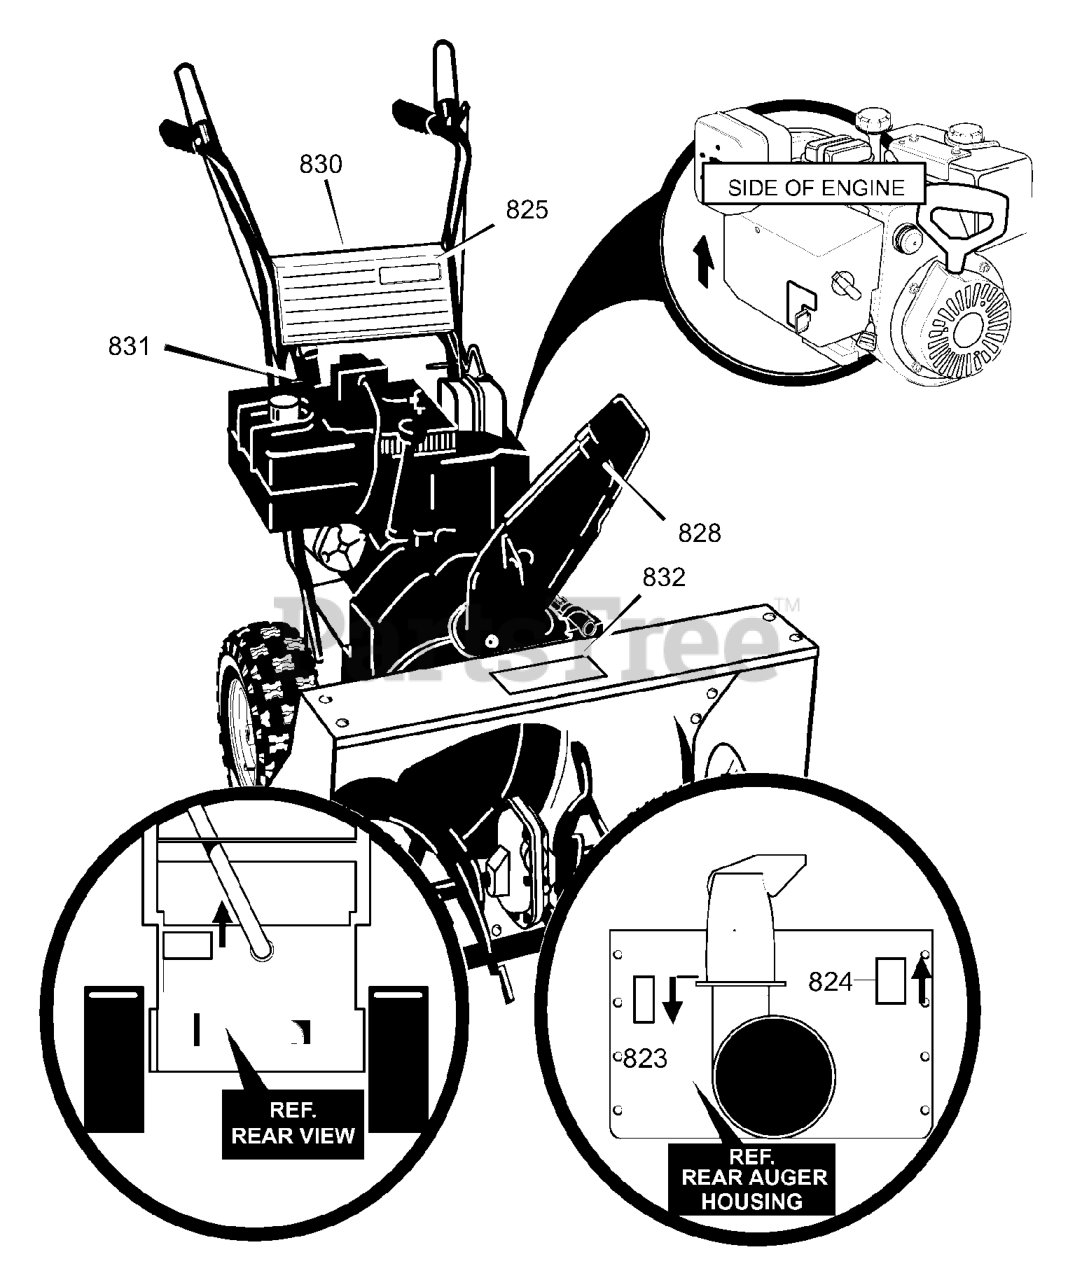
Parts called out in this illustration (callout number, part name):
823	DECAL, DANGER CHUTE HAND
824	DECAL, DANGER FOOT
825	DECAL, NORTHSTAR
828	DECAL, DANGER STRIPE
830	DECAL, TRACTION AUGER DRIVE
831	DECAL, GEAR SELECTOR
832	DECAL, 5/22
